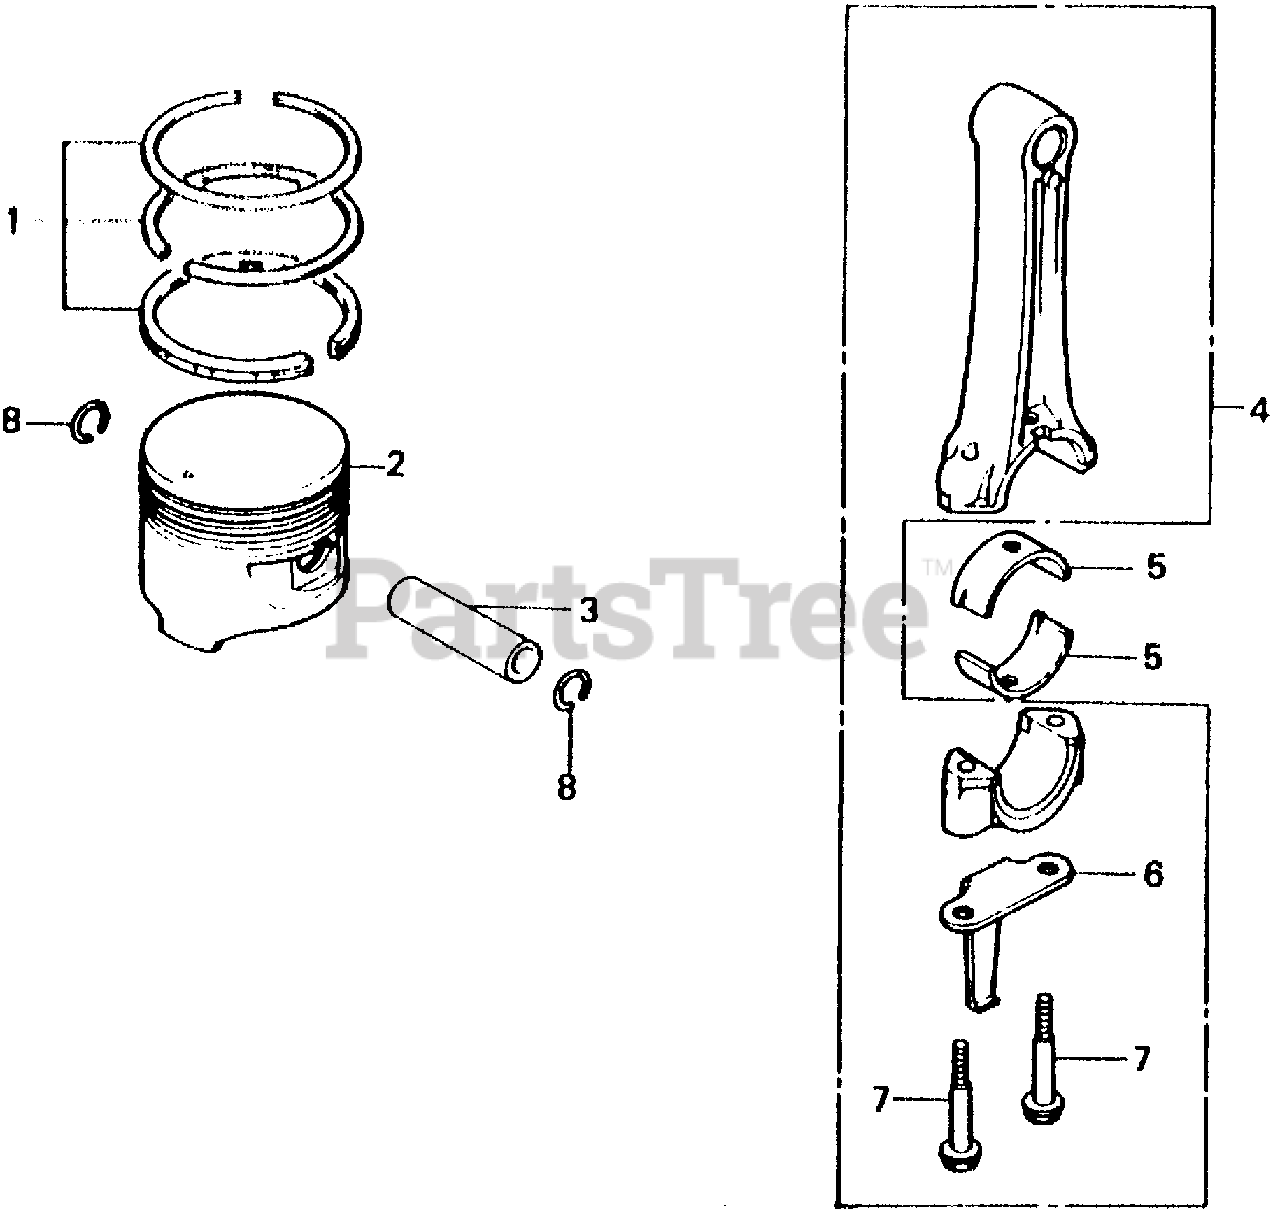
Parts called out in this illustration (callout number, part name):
1	RING SET, PISTON (STD)
1	RING SET, PISTON (STD) (NOT AVAILABLE)
1	RING SET, PISTON (OS 0.25)
1	RING, PISTON (OS 0.50)
1	RING SET, PISTON (OS 0.50)
1	RING SET, PISTON (0.75)
2	PISTON (STD)
2	PISTON (OS 0.25)
2	PISTON (OS 0.50)
2	PISTON (0.75)
3	PIN, PISTON
4	ROD ASSY., CONNECTING
5	BEARING A, CONNECTING ROD
5	BEARING B, CONNECTING ROD
5	BEARING C, CONNECTING ROD
5	BEARING D, CONNECTING ROD
5	BEARING E, CONNECTING ROD
6	DIPPER, CONNECTING ROD
7	BOLT, CONNECTING ROD (8MM)
8	CLIP, PISTON PIN (19MM)
